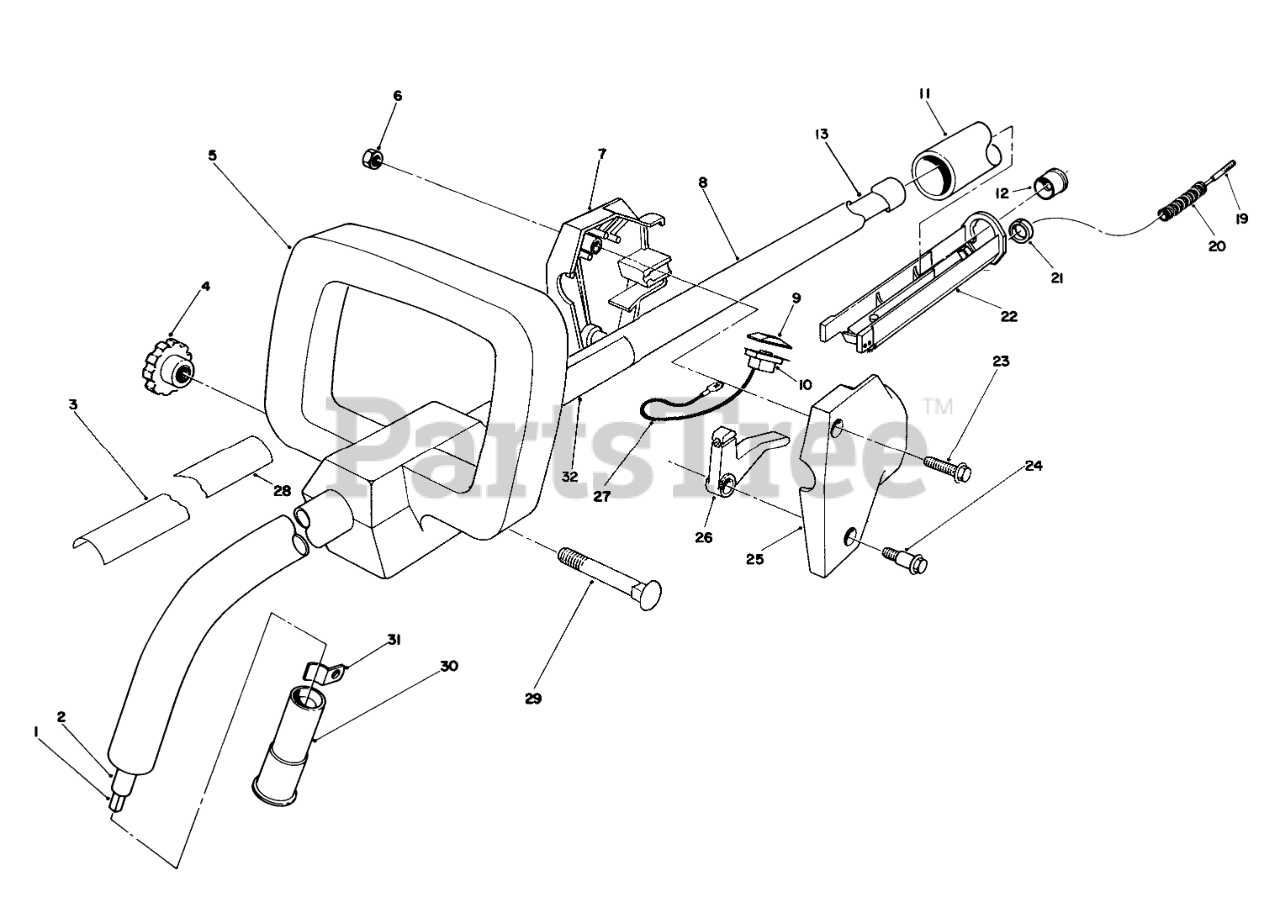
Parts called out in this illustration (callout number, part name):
1	FLEX SHAFT
2	FLEX SHAFT CASING
3	DECAL - TC 2010
5	SECONDARY HANDLE
6	NUT-LOCK, NI
7	RH HOUSING
8	Tube-Curved
9	SWITCH COVER
10	SWITCH
11	GRIP-RUBBER
12	BUSHING
13	Spacer
19	THROTTLE CABLE
20	CABLE COVER
21	RING FITTING
22	TROUGH
24	SCREW-SHOULDER
25	LH HOUSING
26	THROTTLE LEVER
27	WIRE ASM
28	Decal-Warning
29	BOLT-CARRIAGE
30	INSERT-POLE END
31	LOWER TUBE RETAINER
32	DECAL-INSTRUCTION
